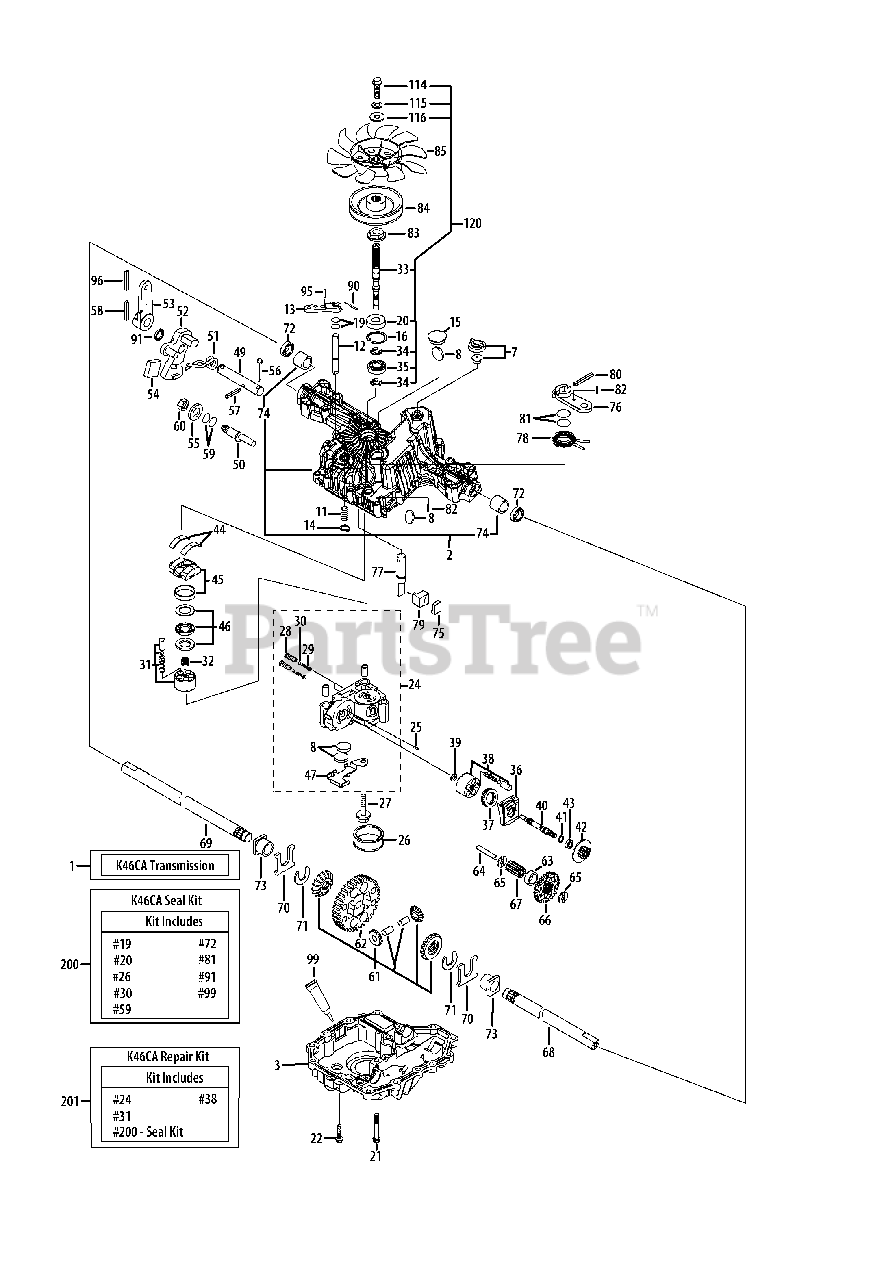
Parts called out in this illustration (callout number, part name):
1	K46CA Transaxle
2	Kit, Upper Case
7	Vent Valve 15
12	Bypass Shaft A
14	Snap Ring 10
15	Sealing Cap 30
16	Snap Ring C 35
19	O-Ring 1A P10A
20	Seal TC 153507
21	Tapping Screw 8 x 55
22	Tapping Screw 8 x 30
24	Kit, Center Case C
26	Filter 105
28	IDS Valve 1.2
30	IDS Filter 300
31	Kit, Cylinder Block (Pump)
34	E-Ring 15
35	Bearing 6202C3
36	Motor Housing
37	Thrust Bearing 51106
38	Kit, Cylinder Block
39	Washer 12 x 24 x 1
41	Snap Ring C15
42	Brake Disc/Motor Gear (11T)
43	Bearing 6202 RSR C3
44	Thrust, Plastic
45	Swash Plate Assembly
46	Kit, Thrust Bearing (Pump)
47	Magnet Holder
49	Control Shaft
51	Torsion Spring, Standard
52	Control Arm A
53	Control Lever F
56	Cotter Pin 1/8" x 3/4"
57	Spring Pin 6 x 36
58	Roll Pin 6 x 40
61	Diff Gear Kit
62	Final Gear (54T)
63	Final Pinion Collar
64	Reduction Shaft
65	Washer 12 x 32 x 3.2
66	Reduction Gear (37T)
67	Final Pinion Gear (10T)
68	Axle Shaft, Left
69	Axle Shaft, Right
70	Thrust Washer
72	Seal 19 x 32 x 8
73	Bushing 19 x 25
74	Bushing 19.05
78	Brake Return Spring
79	Brake Actuator
80	Spring Pin 5 x 32
81	O-Ring 1A P12
82	Spring Pin 4 x 16
83	Spline Collar
90	Spring Pin 3.0A x 20
91	Oil Seal 16 x 22 x 03
95	Spring Pin 3.0A x 16
96	Roll Pin 3.5 x 40
99	Sealant
120	Pump Shaft/Bearing Kit
200	Kit,Seal
201	Repair Kit,
